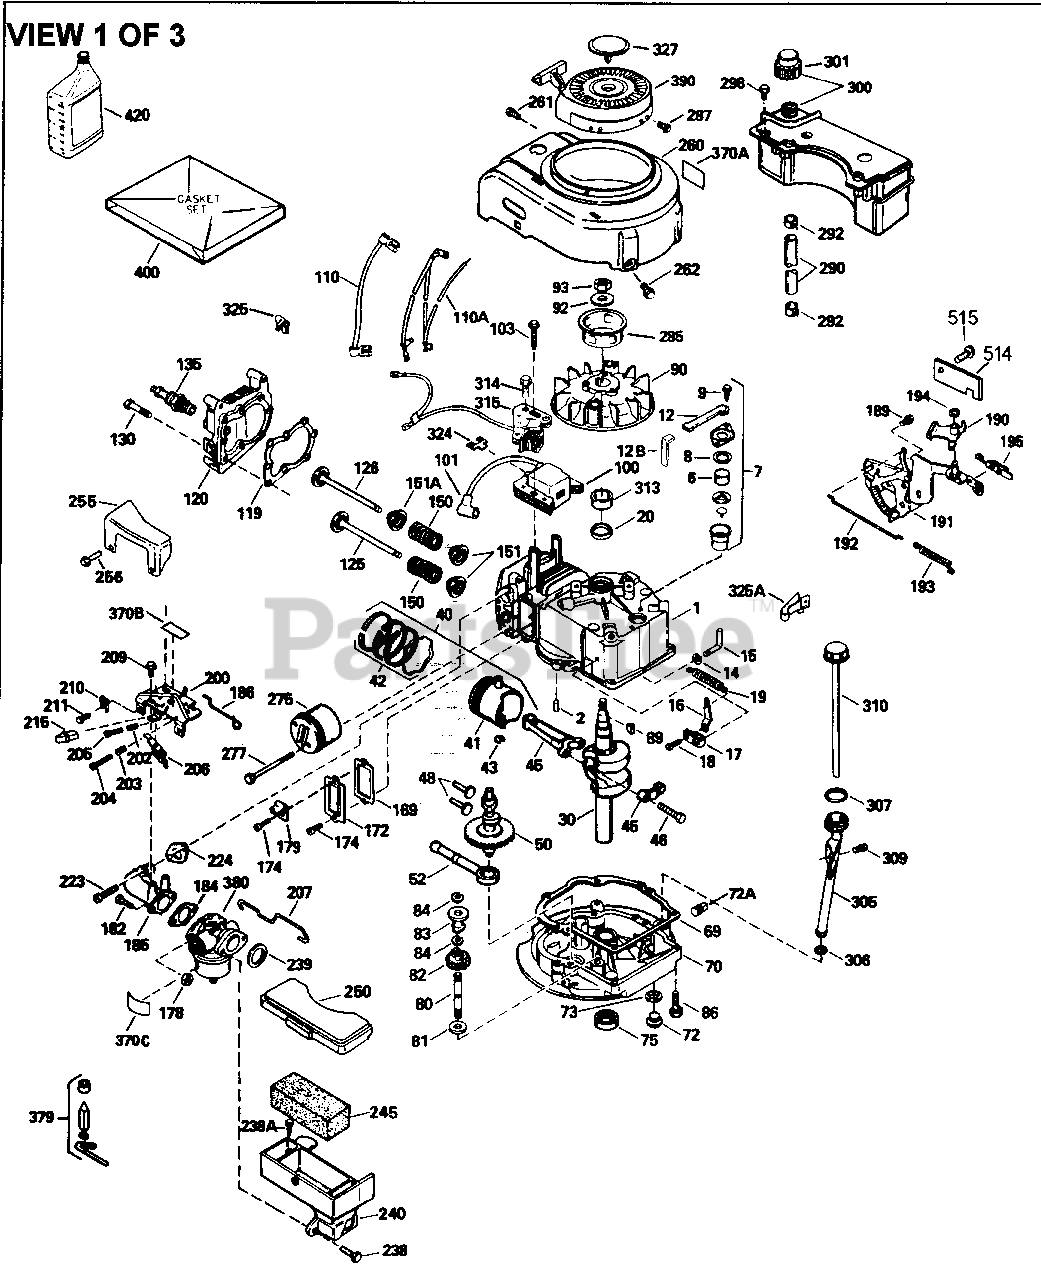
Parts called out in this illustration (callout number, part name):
1	"Cylinder (Incl. 2 & 20) (2-13/16" Bor e ) (Inverted Ports)
2	Dowel Pin
6	Element, Breather
7	Breather Ass'y. Incl. 6, 8, 9, 12 , & 12A
8	* Gasket, Breather
9	Screw, 10-24 x 9/16"
12	Tube, Breather
12A	Elbow, Breather tube
14	Flat Washer
15	Rod, Governor (Incl. 14)
16	Lever, Governor
17	Clamp, Governor lever
18	Screw, 8-32 x 5/16"
19	Spring, Governor
20	Seal, Oil
30	Crankshaft
32	Washer, Thrust NOTE: This thrust wash er maynot be required if a new cranks hafthas been installed. Check the pro per Mechanic's Handbook for acceptabl e end play. Use this .010" thrust was her if excess end play is measured.
40	Piston, Pin & Ring Set (Std.) 2-13/1 6"
40	Piston, Pin & Ring Set (.010" OS)
40	Piston, Pin & Ring Set (.020" OS)
41	Piston & Pin Ass'y. (Incl. 43)(Std.) 2-13/16"
41	Piston & Pin Ass'y. (Incl. 43) .010" OS
41	Piston & Pin Ass'y. (Incl. 43) .020" OS
42	Ring Set (Std.) (2-13/16" Bore)
42	Ring Set (.010" OS)
42	Ring Set (.020" OS)
43	Piston Pin Retaining Ring
45	Rod Assy., Connecting (Incl. 46)
46	Bolt, Connecting rod
48	Valve Lifter
50	Camshaft
52	Oil Pump Ass'y.
64	Screw, T-30, 1/4-20 x 1/2"
64A	Washer, Flat
69	* Gasket, Mounting flange
70	Flange Ass'y. Incl. 72, 72A, 73, 75 & 80
72	Plug, Oil drain (Incl. 73)
73	* Drain Plug Gasket Not req. W/plastic plug
75	Oil Seal
80	Shaft, Governor
81	Washer, Flat
82	Gear Assy., Governor (Incl. 81)
83	Spool, Governor
84	Retaining Ring
86	Screw, 1/4-20 x 1-1/4"
89	Flywheel Key
90	Flywheel
92	Washer, Belleville
93	Nut, Flywheel
100	Solid State Ignition This coil has be en superseded to 730207 solid state c onversion kit
100	Magneto-to-Solid State Conv. Kit (Inc ludes solid state module, solid state flywheel key, and instructions.) (Us e as required on external ignition en gines only.)
101	Cover, Spark plug (Use as required)
103	Screw, 1/4-20 x 5/8"
103	Screw, Torx T-15, 10-24 x 1"
110	Ground Wire
118	Rope Guide Kit (Use as required)
119	* Gasket, Head
120	Head, Cylinder
125	Exhaust Valve (Std.) (Incl. 151) (Inv erted Ports)
125	Intake Valve (Std.) (Incl. 151) (Conv entional Ports)
125	Exhaust Valve (1/32" OS) (Incl. 151) (Inverted Ports)
126	Exhaust Valve (Std.) (Incl. 151) (Con ventional Ports)
126	Intake Valve (Incl. 151) Inverted Po rts
126	Intake Valve (1/32" OS) (Incl. 151) ( Inverted Ports)
127	Washer, Flat
129	Screw, 5/16-18 x 1-1/2"
130	Screw, 5/16-18 x 1-1/2" Use as requir ed
130	Screw, 5/16-18 x 2-1/2" Use as requir ed
135	Resistor Spark Plug - RJ17LM
150	Spring, Valve
151	Cap, Lower valve spring
169	Valve Cover Gasket
172	Cover, Valve spring box
174	Screw, 10-24 x 1/2"
178	Nut & Lock Washer 1/4-28
182	Screw, 1/4-28 x 1"
184	* Gasket, Carburetor
185	Pipe, Intake
186	Link, Governor spring
200	Control Bracket Incl. 203, 204 & 206
203	Spring, Compression
204	Screw, 5-40 x 7/16"
206	Terminal (Use as required)
207	Link, Throttle
209	Screw, 10-24 x 9/16"
210	Conduit Clip
211	Screw, 10-32 x 3/8"
223	Screw, 1/4-20 x 1-1/8"
224	* Gasket, Intake pipe
238	Screw, 10-32 x 1/2"
239A	Air Cleaner Gasket
245	Air Filter (Paper) also available in Packaged Part #740029B
246E	Filter, Pre-air (Use as required)
250D	Cover, Air cleaner
260	Housing, Blower
261	Screw, 10-24 x 9/16"
262	Screw, 1/4-20 x 15/32"
275E	Muffler (Incl. 274)
277	Screw, 1/4-20 x 2-3/8" Use as requir ed
277	Screw, 1/4-20 x 2-1/4" Use as requir ed
277	Screw, 1/4-20 x 2-1/2" Use as requir ed
287	Screw, 1/4-20 x 5/8"
290	Fuel Line (8.62") as req.)
290	Fuel Line (Braided 16")(40 cm) Use as req.
290	Fuel Line (Braided 32")(81 cm) Use as req.
290	Fuel Line (Epichlorohydrin 6-3/4") 17 cm
292	Fuel Line Clamp
298	Screw, 10-32 x 35/64"
301	Fuel Cap (Red 1-1/2" ID) also availab le in Packaged Part #740005B
305	Oil Fill Tube
306	Gasket, Oil fill tube
306	"O" Ring This "O" ring is required wi th metal fill tube only when replacem ent mounting flange with .777 dia. oi l fill hole has been used.
307	"O" Ring
309	Screw, 10-32 x 1/2"
310	Oil Dipstick (Incl. 150)
313A	Gasket, Stator
326	Plug, Screen
359	Guard, Flywheel
370H	Decal, Instruction (Optional)
370J	Decal, Instruction (Optional)
377	Breaker Points (also available in Pac kaged Part #740037B)
378	Condenser (also available in Packaged Part #740037B)
379	Inlet Needle, Seat & Clip Assy.
380	Carburetor (Incl. 184) (Refer to Divi sion 5, Section A, Page A1-14 or Fich e 8A, Grid E-1 for breakdown)
390A	Side Mount Rewind Starter Refer to Di vision 5, Section C, page 32 or Fiche 8A, Grid G-3 for breakdown
400	* Gasket Set (Incl. items marked *)
420	SAE 30, 4-Cycle Engine Oil (Quart)
425	Starter Muff Kit (Incl. 370J,426,427) Opt.
426	Starter Air Cleaner (Optional)
427	Starter Air Cleaner Bracket Optional
436	Stator Plate Ass'y. Incl. 377,378,437 , 442-448
437	Spring, Breaker box cover
438	Cover, Dust
439	Gasket, Stator cover
440	Cam, Breaker
443	Nut, 8-32
444	Breaker Fastening Screw & Washer
445	Condenser Fastening Screw
446	Terminal, Ground
448	Felt, Cam wiper
